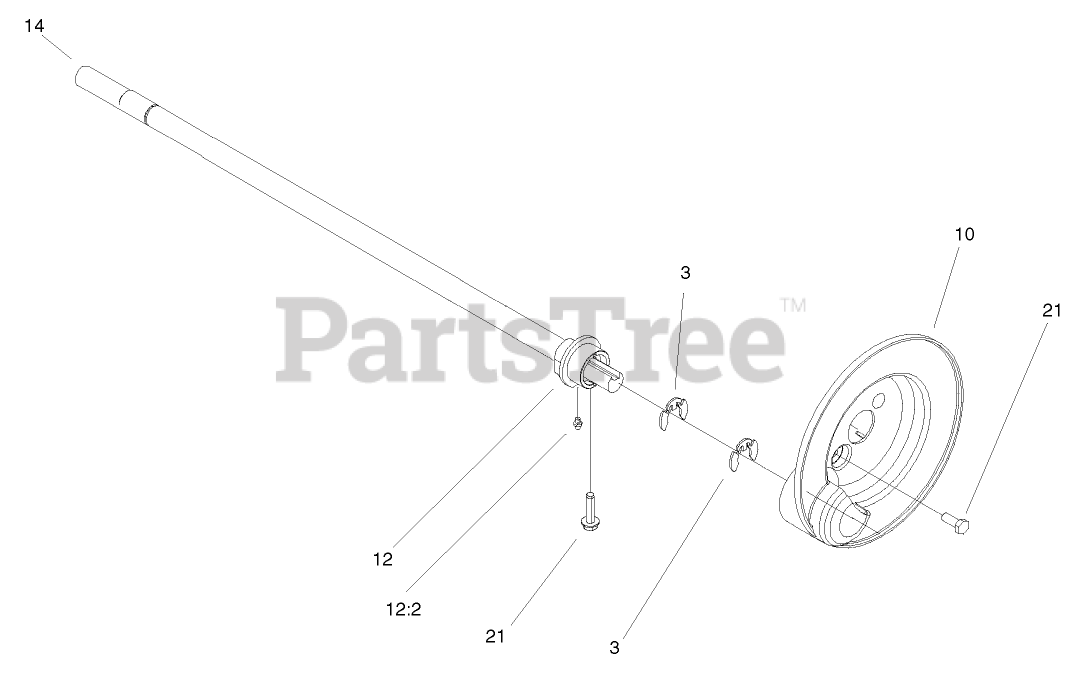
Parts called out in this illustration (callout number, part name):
3	RING-RETAINING,CLIP
10	COVER-GEAR
12	BUSHING ASM
12:2	FITTING-GREASE
14	SHAFT-PIVOT
21	SCREW-TAPTITE
